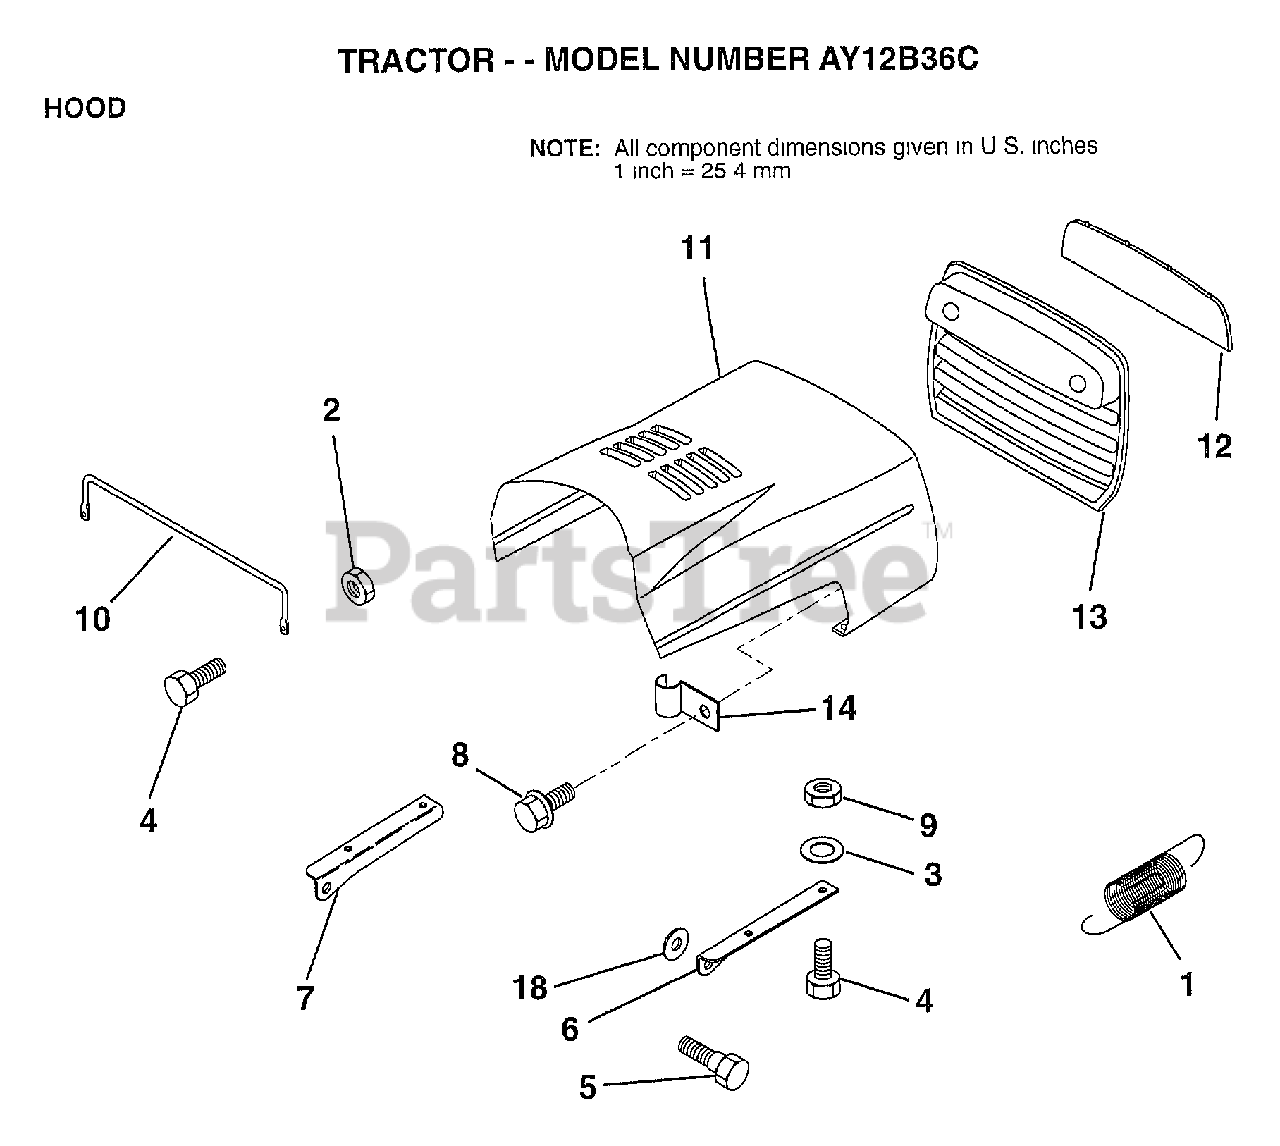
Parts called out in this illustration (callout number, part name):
1	EXT SPRING
2	NUT
3	WASHER
5	BOLT.SHLD.5/16-18
6	BRKT HOOD RH
7	BRKT HOOD LH
8	"SCREW,HWHD.HI-LO#13-16X3/4"
9	NUT
10	"BRACE,HOOD"
11	HOOD.IMPREG.MS550
12	LENS
13	GRILL
18	WASHER
